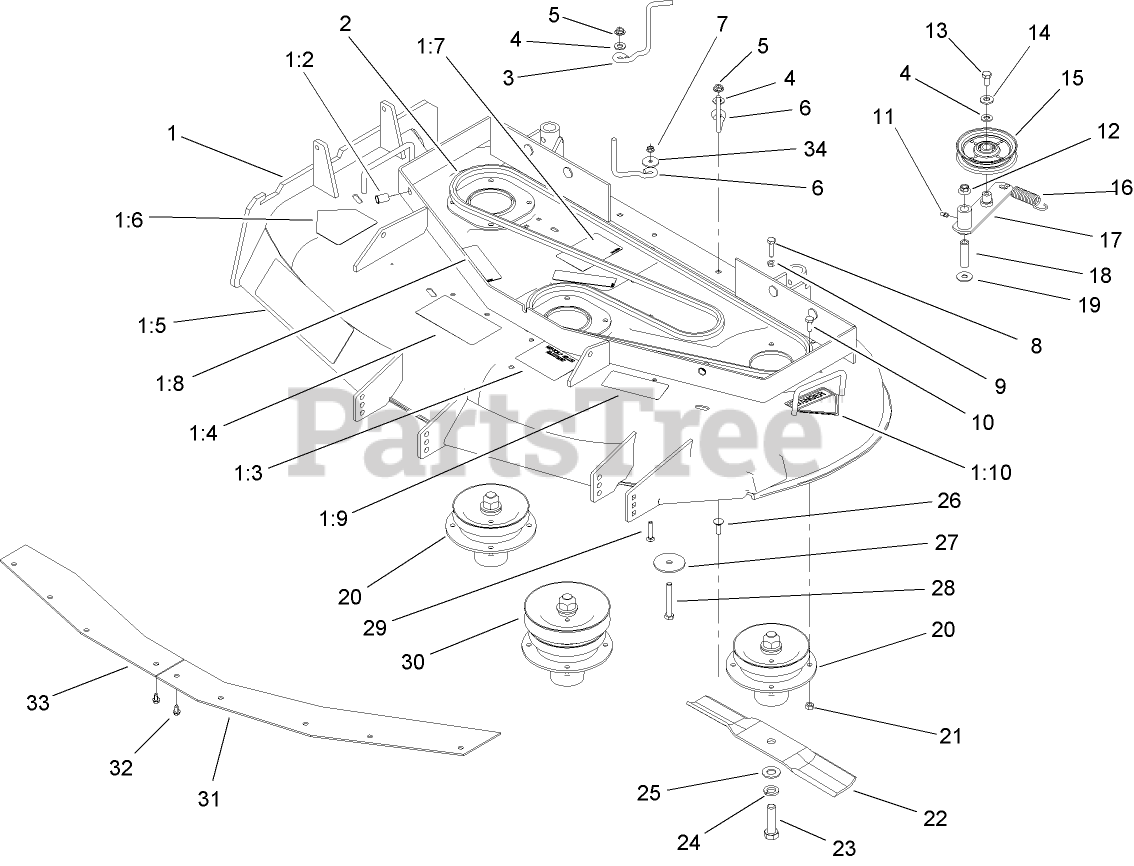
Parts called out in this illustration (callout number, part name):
1	DECK ASM
1:2	INSERT-NUT
1:3	DECAL-ANTI SCALP
1:4	DECAL-DANGER, THROWN OBJECT
1:6	DECAL-DANGER
1:7	DECAL-ROUTING, BELT
1:8	DECAL-DANGER
1:9	DECAL-TORQUE
1:10	DECAL-DANGER
2	V-BELT
3	Guide-Belt
4	WASHER-FLAT
5	NUT-HF
6	ROD-BELT
7	NUT-LOCK, HHF
8	SCREW-HH
9	NUT-JAM
10	SCREW-HH
11	FITTING-GREASE
12	NUT-HF
13	SCREW-HH
14	WASHER-BELLEVILLE
15	PULLEY-IDLER
16	Spring-Extension
17	IDLER ARM ASM
18	TUBE-IDLER
19	WASHER
20	Spindle Housing ASM
21	NUT-LOCK, CONE
22	Blade
23	SCREW-BLADE
24	WASHER-LOCK
25	WASHER-FLAT
26	BOLT-CARR
27	WASHER-END
28	SCREW-HH
29	SCREW-CARR
30	Spindle Housing ASM
31	PLATE-BLOWOUT, LH
32	SCREW
33	PLATE-BLOWOUT, RH
34	Washer-Retainer, Pulley
